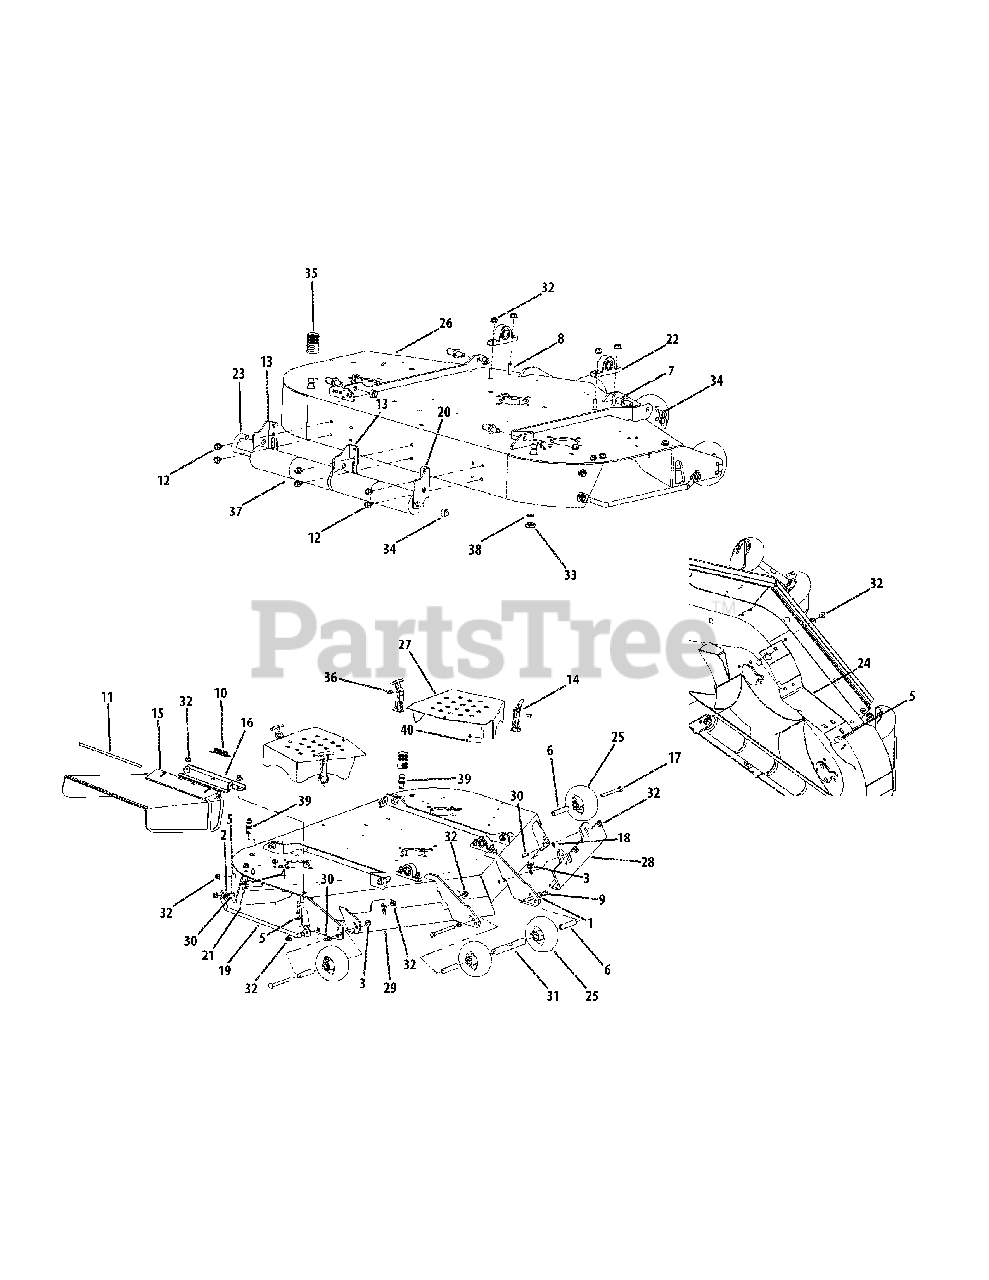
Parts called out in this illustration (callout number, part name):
1	Lock Washer, 3/8
2	Flat Washer, 3/8
3	Flange Lock Hex Nut, 3/8-16
4	Idler Washer
5	Carriage Bolt, 3/8-16 x .75 Lg.
6	Wheel Spacer
7	Pin, 5/8 Dia. x 1.2 Lg.
8	Carriage Bolt, 3/8-16 x 1.25
9	Hex Cap Screw, 3/8-16 x 4.50
10	Torsion Spring, 0.4ID x 2.16Lg
11	Chute Deflector Rod
12	Hex Index Washer Screw, 3/8-16, .05
13	Deck Roller Mount Bracket LH
14	T-Handle Latch Draw
15	Deflector Chute
16	Deflector Chute Bracket
17	Carriage Bolt, 3/8-16 x 4.00
18	Push Retainer
19	Finger Guard
20	Deck Roller Mounting Bracket, RH
22	Pillow Block, Steel
23	J-Hook w/ Threaded Roller
24	48" Adjustment Baffle
25	Complete Wheel, 5.00 Dia.
26	48" Deck Assembly
27	Deck Belt Cover
28	Left Hand Front Adjustment Skirt
29	Right Hand Front Adjustment Skirt
30	Carriage Bolt, 3/8-16 x 1
31	Ball Wheel Mounting Shaft
32	Lock Nut, Nylon Insert, 3/8-16
33	Hex Nut, M16-1.5
34	Lock Nut, Nylon Insert, 1/2-13
35	Water Nozzle Adaptor
36	Phillips Head Screw, #10-32 x 1/2
37	Front Roller
38	Lock Washer, 17 x 23.8 x 1.95
39	Deck Water Nozzle
40	Lock Nut, Nylon Insert, #10-32
